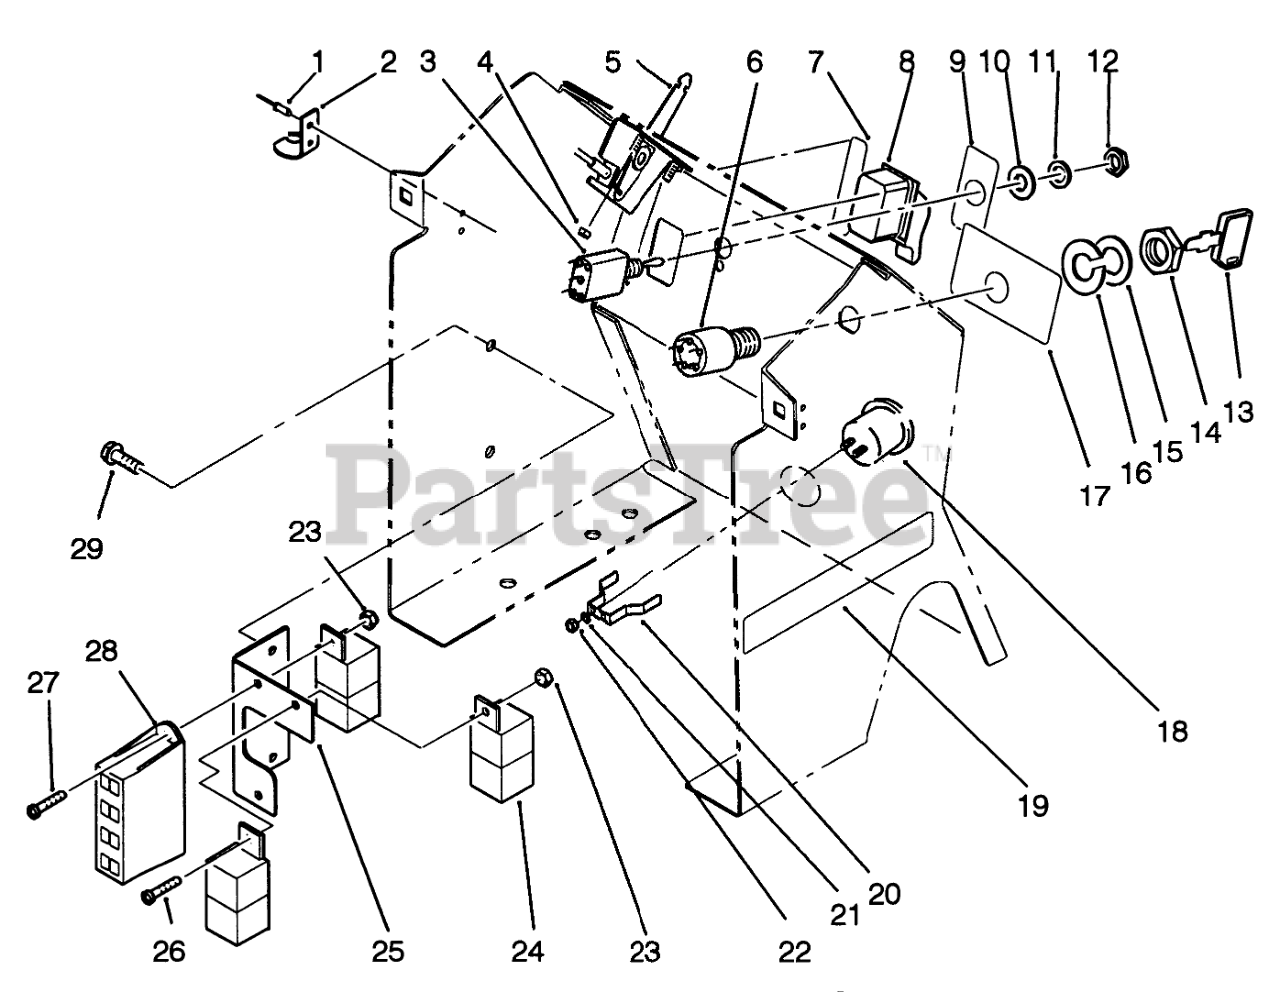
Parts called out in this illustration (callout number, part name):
1	POPRIVET 1/8X 1/8 BK
2	KEEPER-LATCH
3	SWITCH-LIGHTS
4	Nut
5	CONTROL-THROTTLE
6	Switch-Ignition, Assembly (Incl. Ref #6 & 13-17)
7	DECAL-PTO
8	PTO-SWITCH W/COVER
9	DECAL-LIGHTS
10	WIRE ASSY
11	Washer
13	Key
15	Washer
16	LOCKWASHER
17	DECAL-IGNITION
18	HOUR-METER
19	DECAL-MODEL 5-SPEED
20	CLAMP-HOUR METER
21	NUT-LOCK, NI
22	Nut
23	Nut
24	RELAY
25	Bracket-Fuse Holder
26	SCREW-PPH
27	Screw
28	FUSE-HOLDER 4 WAY
29	TRS-1/4-20X1/2 BLACK
